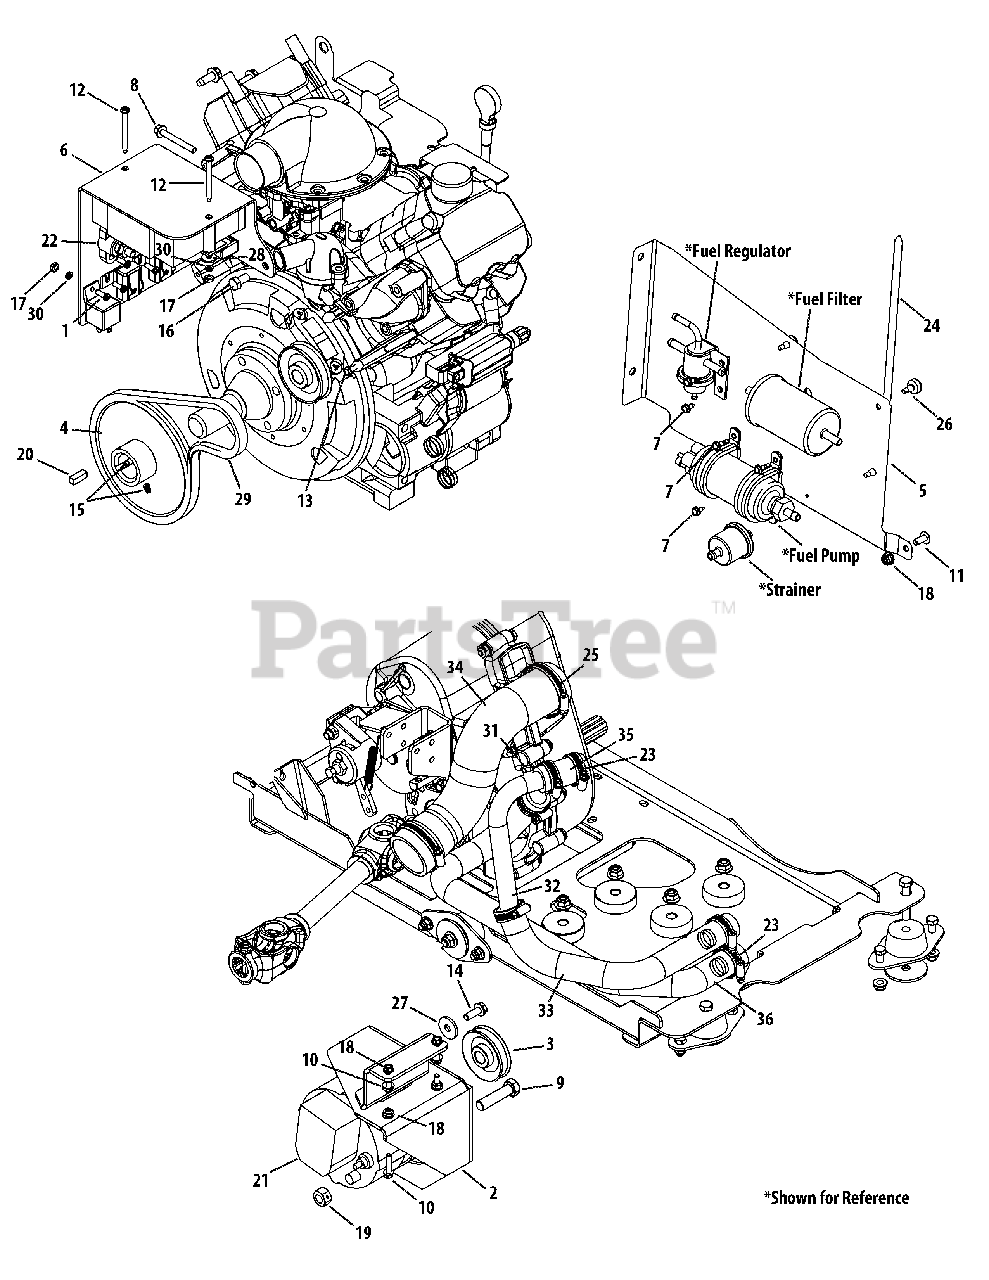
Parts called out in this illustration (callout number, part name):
1	Screw
2	Supt, Asm, Altnr, UV, Kohler
3	Pulley, 2.65 OD x 3L
4	Pulley, 6.00 OD x 1.125
5	Brkt, Fuel System, Kohler EFI
6	Brkt, Electrical, Kohler EFI
7	Screw, #10-16 x .500
8	Screw, M6-1
9	Hhcs, 1/2-13 x 2.00
10	Scr, tt, 1/4-20 x 1.00
11	Scr, Mach, 1/4-20 x .625
12	Scr, Mach, #10-32 x 2.00
13	Scr, #10-32 x .625
14	Scr, 5/16-18 x .875
15	Scr, 1/4-20 x 3/8
16	Hhcs, M8-1.25
17	Nut, Hex, #10-32
18	Nut, Flglk, 1/4-20
19	Nut, Hexlk, 1/2-13
20	Sq key, 1/4 x .75lg
21	Altrnr, Aux, 65 Amp
22	Elec, Power, Distribution Post
23	Clamp, Hose, Adj
24	Tie, Cable
25	Clamp, Hose, Adj
27	Wash, Flat, .344 x 1.125 x .12
28	Wash, Flat, .194 x .62 x .063
29	Belt, V-Type
30	Wash, Lock
31	Ftg, Petcock
32	Tube, Rdtr
34	Hose, Air Inlet
35	Hose, Rdtr, Top Rear
36	Hose, Rdtr, Lower Rear
